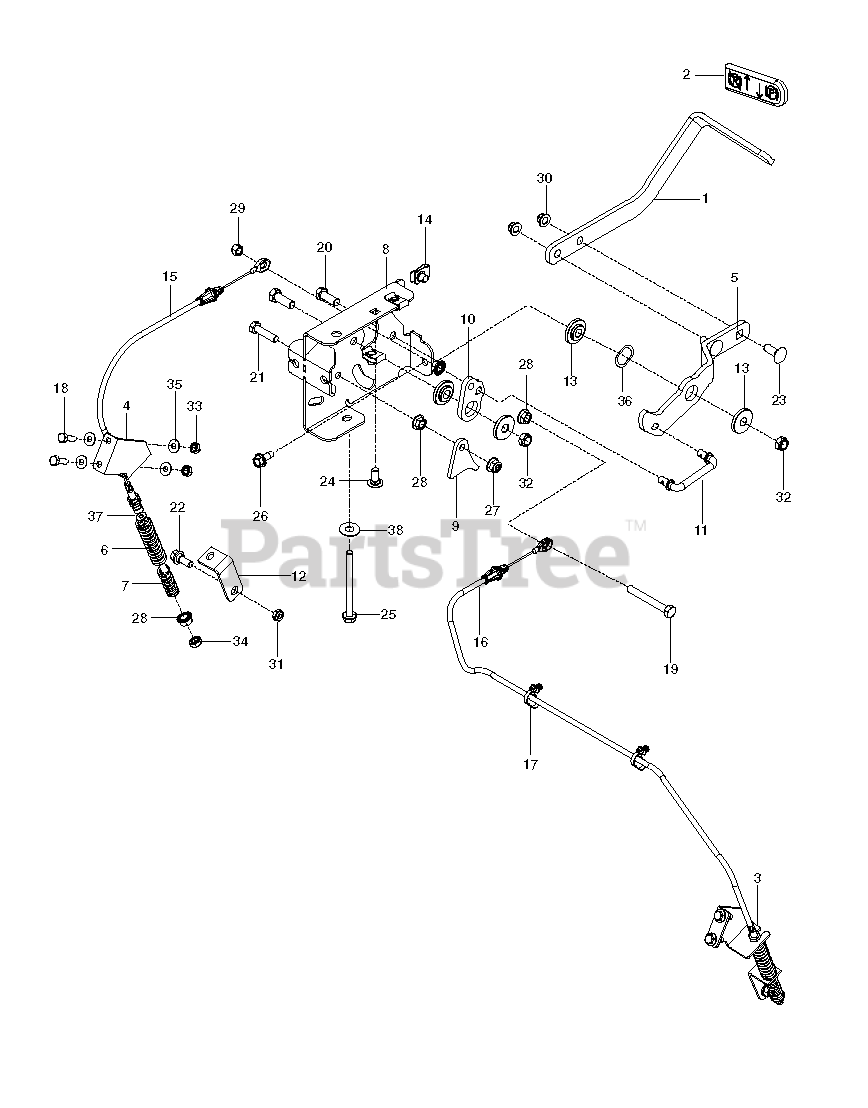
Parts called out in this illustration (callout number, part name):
1	ARM, BRAKE
2	GRIP, PARK BRAKE
3	BRKT, BRAKE RT, BLK
4	BRKT, BRAKE LT, BLK
5	LEVER, BRAKE
6	SPRING, RETURN
7	SPRING, ENGAGEMENT
8	MOUNT, BRAKE WLDMT
9	ACTUATOR, SWITCH
10	BELLCRANK, BRAKE
11	LINKAGE, BRAKE
12	BRKT, BRAKE, BLK
13	BUSHING, BRAKE
14	U-CLIP 5/16-18 NUT RETAINER
15	CABLE, BRAKE, SHORT
16	RP_CABLE, BRAKE, LONG
17	TIE WRAP, 8-3/8", W/CLIP
18	HCS 1/4-20X7/8 GR5
19	HCS 5/16-18 X 2 1/2 TPBLT
20	HCS 3/8-16X1.GRD.5.ZD
21	HCS 5/16C X 1
22	BOLT, SHOULDER
23	RHSNB 3/8C X 1
24	BOLT 5/16C X 3/4" CARRIAGE
25	HHFS 5/16-18 X 3 3/4
26	BOLT 5/16-18 X 3/4
27	5/16-18 NYLOC FLANGE NUT
28	NUT 5/16C WHIZ
29	NUT 5/16 NYLOC
30	NUT 3/8-16 HEX FLG NYLOC ZD
31	5/16-18 THIN PROF NY
32	NUT HEX 3/8-16 NYLON, THIN
33	NUT.1/4-20.HEX.NYLOC.ZD
34	NUT 5/16-18 HEX JAM ZD
35	WASHER 1/4 SAE
36	WASHER, .825 X 1.087, WAVE
37	WASHER 3/8 SAE FLAT
38	WASH USS FLAT 1/2
